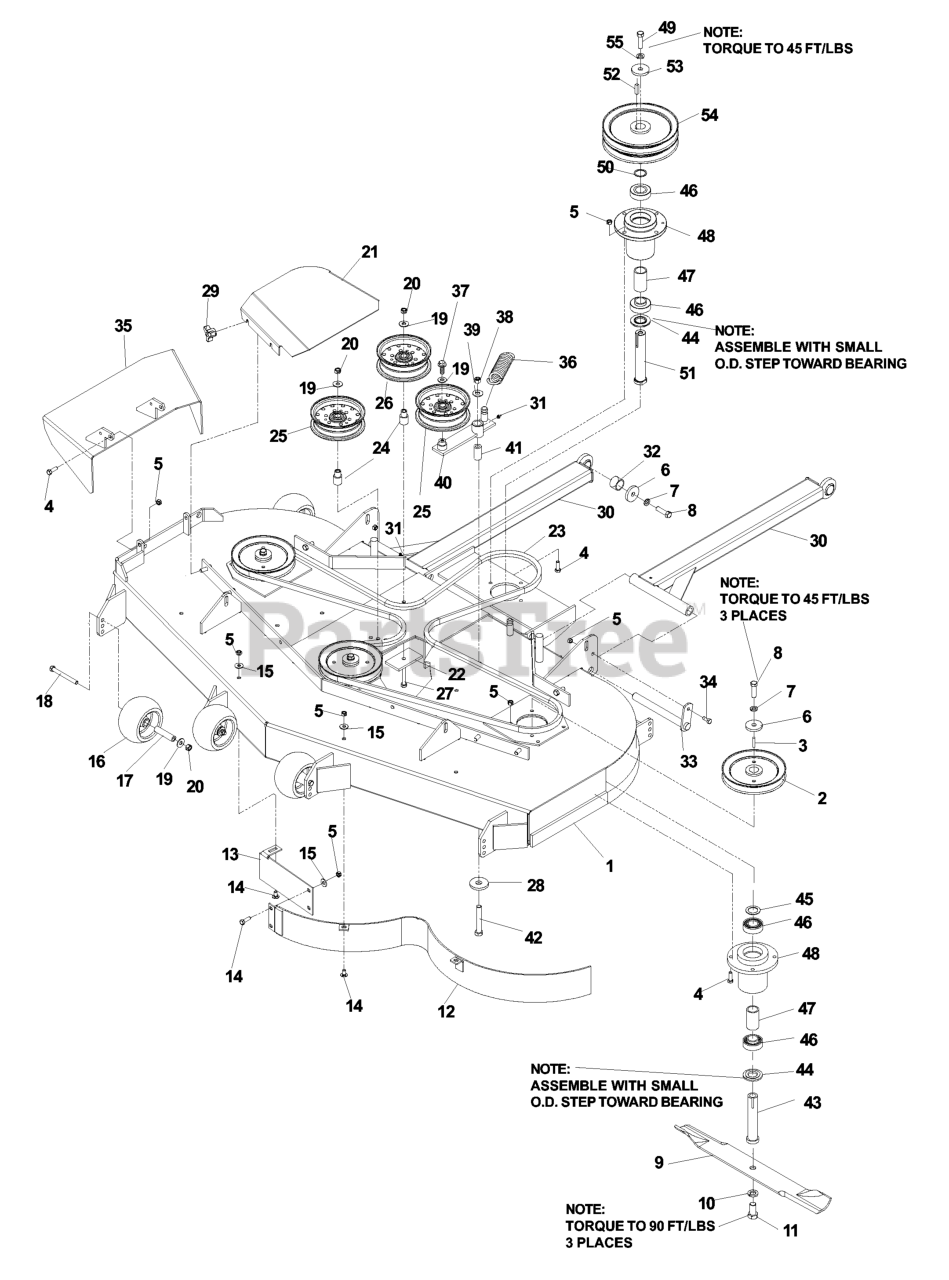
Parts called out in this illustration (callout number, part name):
1	DECK W/DECALS 61" HUS WSL
3	KEY 1/4 SQ X 1 1/8
4	HCS 5/16C X 1
5	NUT 5/16C CENTERLOCK
6	SPINDLE WASHER
7	WASHER 7/16 LOCK
8	HCS 7/16F X 1 1/2
9	BLADE OEM 21" (61" DECK)
10	LOCKWASHER 5/8
11	HCS 5/8F X 1 1/4
12	MAIN BAFFLE - 61" BLK
13	CENTER BAFFLE - 61
14	CARRIAGE BOLT 5/16C X 5/8"
15	WASHER 5/16 FLAT
16	ANTI-SCALP ROLLER
18	HCS 3/8C X 3 1/2
19	WASHER 3/8 FLAT
20	NUT 3/8C CENTERBLOCK
21	61 B.S.PAINTED, RT
22	SUPPORT PLATE
23	BELT, DECK
24	IDLER BUSHING
25	IDLER PULLEY
26	IDLER PULLEY (TALL)
27	HCS 3/8C X 2 1/2
28	WASHER, SUPPORT
29	KNOB, THREE PRONG
30	STRUT WELDMT, L.H.
31	ZERK
32	SPACER, STRUT
33	PIN WELDMENT
34	HCS 5/16C X 3/4
35	CHUTE 61 ORANGE
36	DECK SPRING
37	4CS 3/8C X 1 SERRATED HEAD
38	NUT 1/2-13 HEX NYLOC ZD
39	WASHER 1/2 FLAT
41	PIVOT BUSHING
42	HCS 1/2C X 3 1/4
44	COMBO SPACER
45	BUSHING.MACHINE.18.GAUGE
46	BEARING
48	HOUSING, DIE CAST
49	HCS 7/16F X 1 1/2
50	BUSHING.MACHINE.18.GAUGE
51	SPINDLE SHAFT
52	KEY 1/4 SQ X 1 1/8
53	SPINDLE WASHER
54	SHEAVE WSL
55	WASHER 7/16 LOCK
